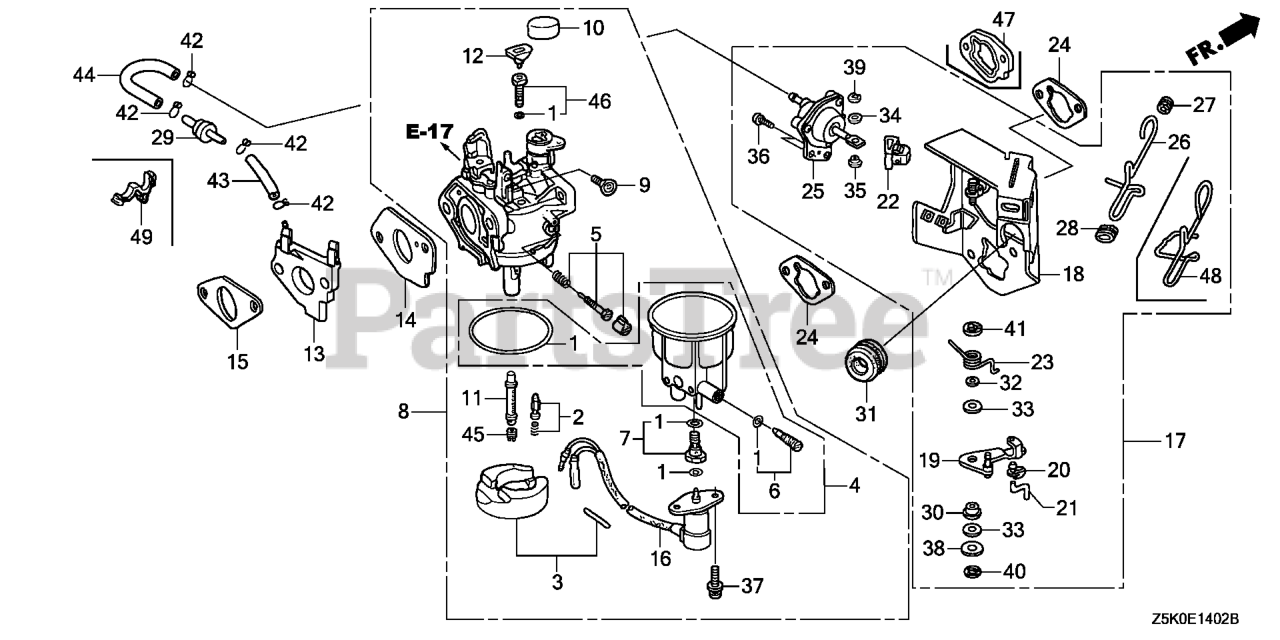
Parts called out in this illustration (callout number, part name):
1	GASKET SET
2	VALVE SET, FLOAT
3	FLOAT SET (CARBURETOR NO.)
4	CHAMBER SET, FLOAT
5	SCREW SET (CARBURETOR NO.)
6	SCREW SET, DRAIN (ADVENTURE GREEN) (CARBURETOR NO.)
8	CARBURETOR ASSY. (BE98L C)
9	SCREW, THROTTLE STOP
10	CAP, CHOKE LEVER DUST
11	NOZZLE, MAIN
12	COLLAR, SET
13	INSULATOR, CARBURETOR
14	GASKET, CARBURETOR
15	GASKET, INSULATOR
16	VALVE ASSY., SOLENOID
17	STAY ASSY., MANUAL CHOKE
18	STAY, SOLENOID
19	LEVER, CHOKE
20	JOINT, ROD
21	ROD, CHOKE
22	STOPPER, CHOKE ROD
23	SPRING, MANUAL CHOKE
24	GASKET, AIR CLEANER
25	DIAPHRAGM ASSY.
27	GROMMET, CHOKE ROD
28	GUIDE, CHOKE ROD
29	VALVE, DASHPOT CHECK
30	BUSH, ARM PIVOT
31	GROMMET, FENDER
32	WASHER, CHOKE LEVER
33	SEAL, CHOKE LEVER
34	WASHER, THRUST (2.7X8)
35	COLLAR, LEVER
36	SCREW, PAN (5X12)
37	SCREW-WASHER (5X12)
38	WASHER, PLAIN (5MM)
39	E-RING (2MM)
40	E-RING (4MM)
41	E-RING (7MM)
42	CLIP, TUBE (B7)
43	BULK HOSE, VACUUM (3.5X8000) (3.5X130)
44	BULK HOSE, VACUUM (3.5X8000) (3.5X130)
45	JET, MAIN (#82)
45	JET, MAIN (#85) Use up to Engine SN BE81B B.
45	JET, MAIN (#88) Use up to Engine SN BE81B B.
46	JET SET, PILOT (#45) (CARBURETOR NO.)
47	SPACER, CARBURETOR
48	ROD, CHOKE CONTROL
49	CLIP, WIRE HARNESS
